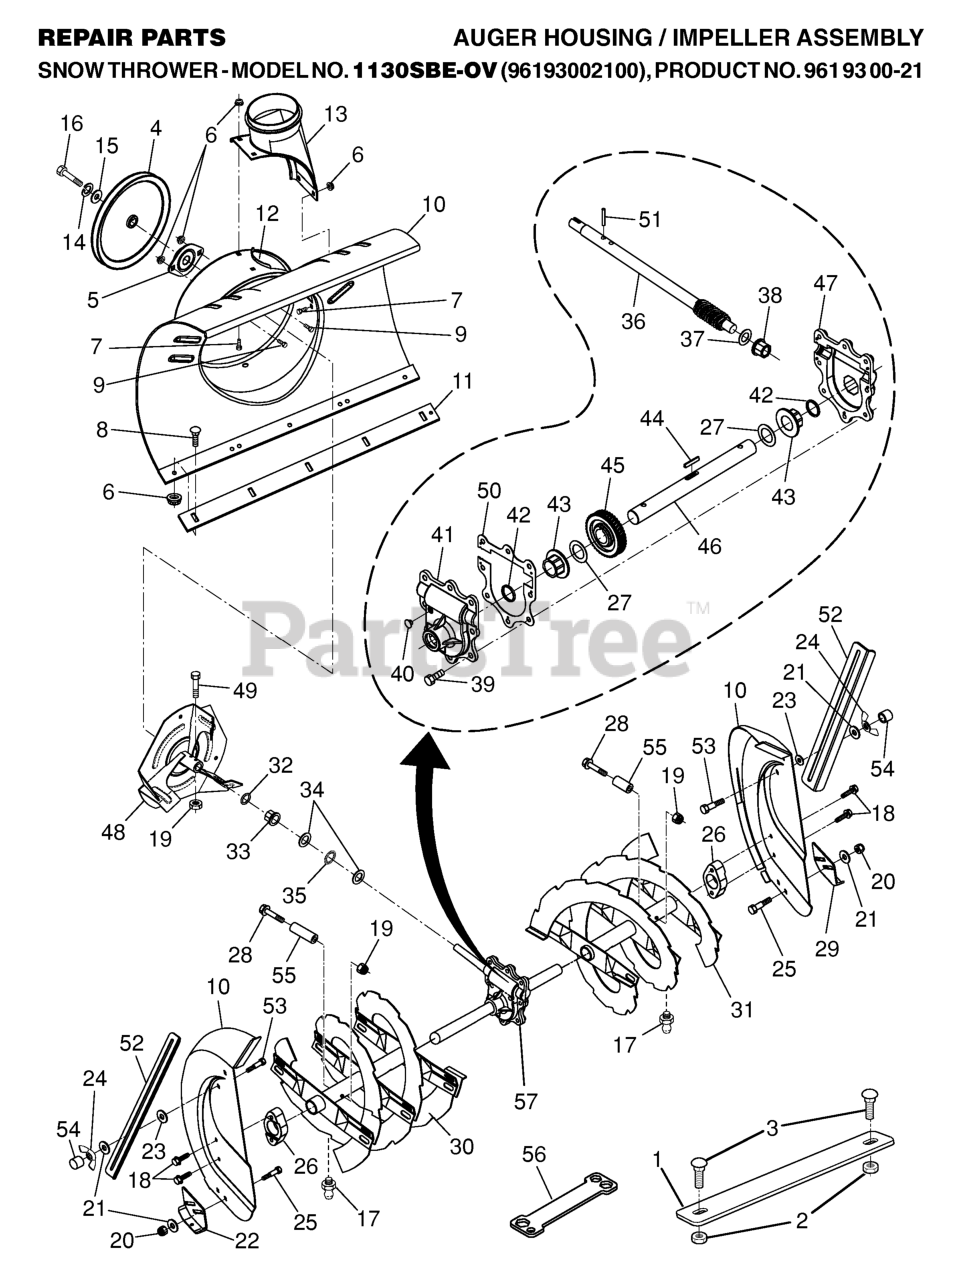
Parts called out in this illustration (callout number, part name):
1	WEIGHT AUGER HOUSING 30
2	NUT.LOCK.5/16-18
3	BOLT.CARRIAGE.5/16-18
4	PULLEY, IMPELLER
5	BEARING FLANGE
6	NUT, HEX FLANGE 5/16-18
7	BOLT.CARRIAGE.5/16-18X
8	BOLT
10	HOUSING, AUGER
11	BAR, SCRAPER
12	BRACKET, CORNER DISCHARGE
13	BASE DISCHARGE CHUTE
14	WASHER, LOCK 5/16
15	WASHER, FLAT
16	Screw, Hex Head 5/16-18 x 3/4
17	GREASE FITTING
18	SCREW, HEX HD 5/16X1
19	LOCKNUT.NYLOC.1/4-20
20	NUT, HEX FLANGE 5/16-18
21	WASHER.12021.438X.75X.06.PLS
22	SKID PLATE
24	NUT WING PM
25	BOLT
26	BEARING, AUGER
27	WASHER TRUST 1"
28	BOLT, SHEAR
29	SKID PLATE
30	AUGER ASSEMBLY, RH
31	AUGER ASSEMBLY, LH
33	BUSHING, FLANGE 3/4
34	WASHER, THRUST 3/4
35	BEARING TRUST 3/4 NTA-1220
36	SHAFT, IMPELLER
37	WASHER, THRUST 5/8
38	FLANGE BUSHING-5/8
39	HEX SCREW-5/16 X 3/4
40	CASE PLUG
41	GEARBOX HOUSING-RH
42	OIL SEAL
43	FLANGE BUSHING-1"
44	KEY, SQUARE 1/4 X .875
45	WORM GEAR
46	AUGER SHAFT
47	HOUSING.GEARBOX.LH(SERVICE)
48	IMPELLER ASSY
49	SCREW.HEX.HD1/4-20X
50	GEARBOX GASKET
51	PIN, ROLL 3/16 X 1-1/8
52	BAR, DRIFT
53	BOLT, HEX HEAD
54	STOP.11261.PLASTIC.30X50L.RED
55	SPACER.3943.SLEEVE.250X.47
56	RP WRENCH, SNOWTHROWER
57	GEARBOX.ASSEMBLY.AUGER
